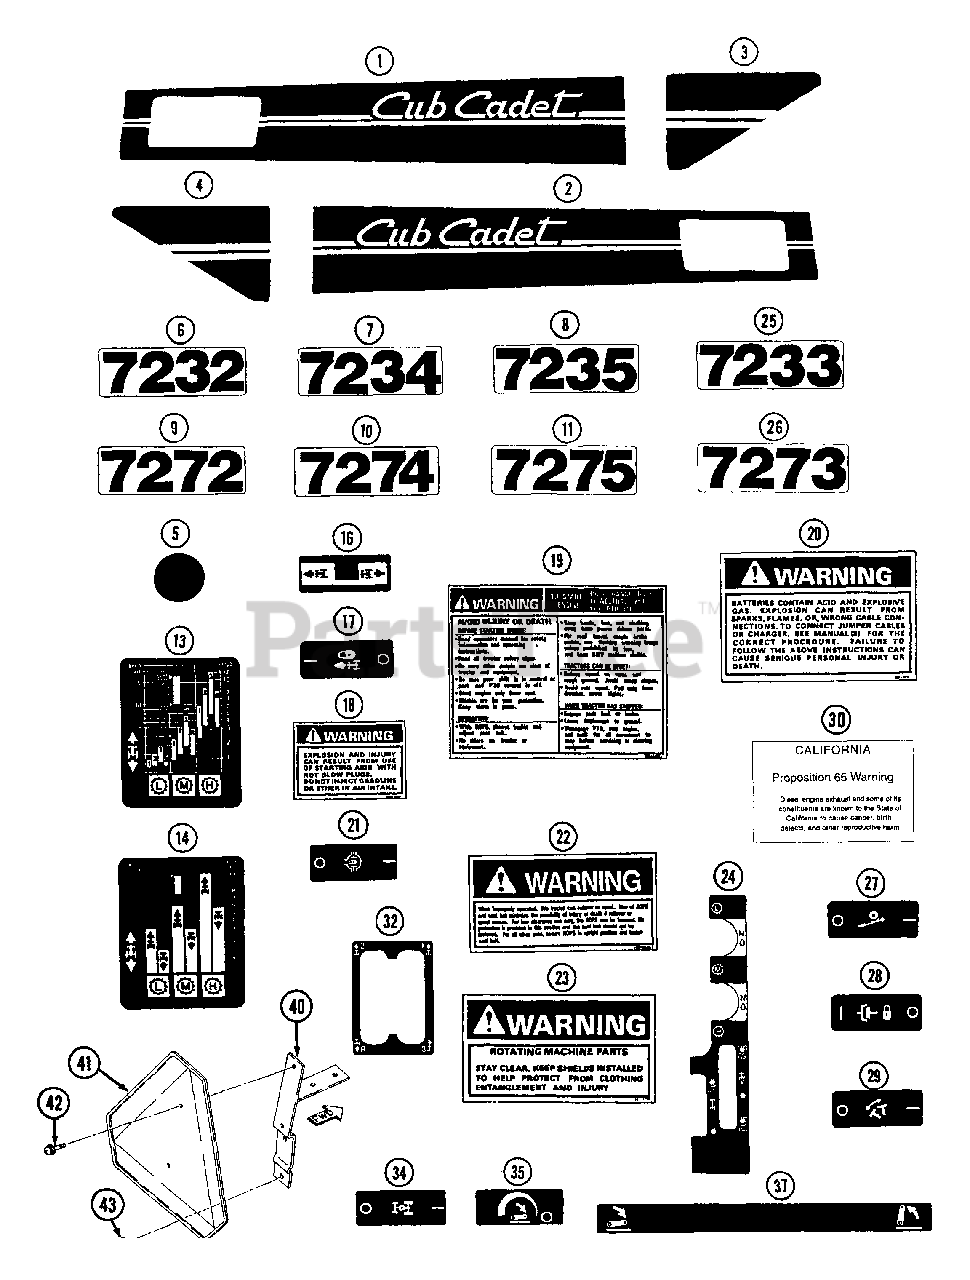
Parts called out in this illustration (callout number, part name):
1	Label, Side L.H.
2	Label, Side R.H.
3	Label, Rear L.H.
4	Label, Rear R.H.
5	Label, Steering
6	Label, Model 7232
7	Label, Model 7234
8	Label, Model 7235
16	Label, AST Control
17	Label, SP Control
18	Label, Warning
19	Label, Warning
20	Label, Warning
21	Label, Diff. Lock
22	Label, Warning
23	Label, Warning
25	Label, Model 7233
28	Label, Declutch
30	Label, Proposition
37	Label, Position
41	Emblem, SMV
